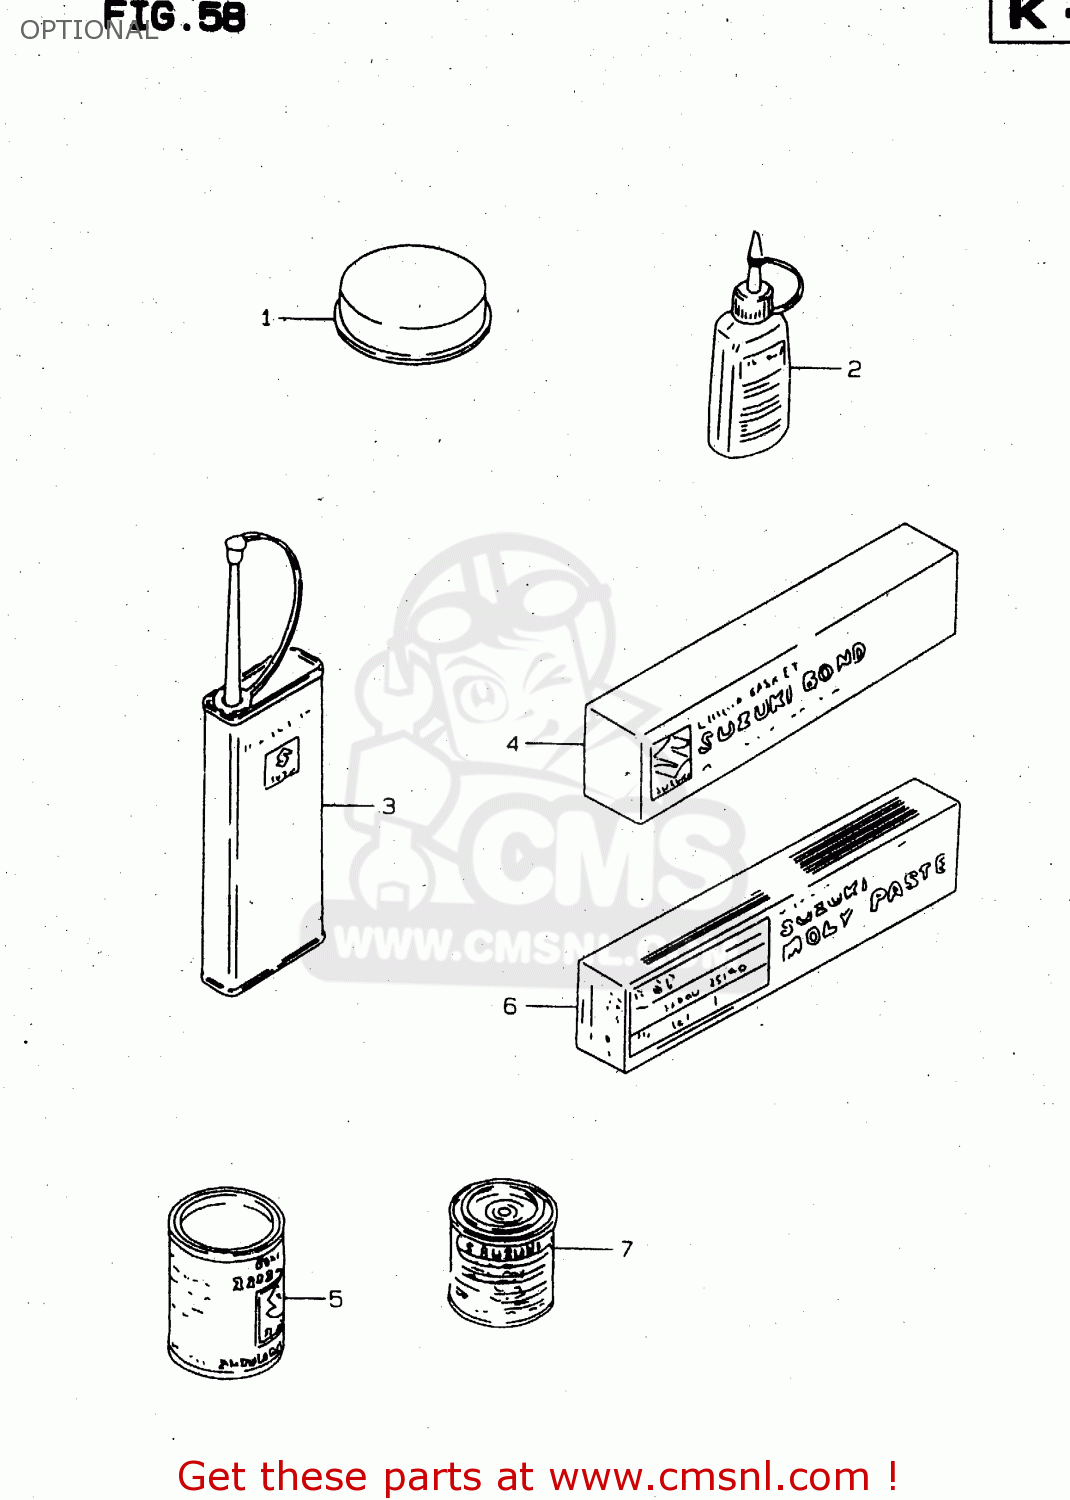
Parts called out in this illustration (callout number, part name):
1	GREASE,PBC FOR BRK PAD 20G
2	THREAD LOCK NO.1342
3	THREAD LOCK NO.1401 CLEAR 200G
4	LIQUID GSKT NO.1215 250G
5	GREASE(C)EP2 LITHIUM 150G
6	SUZUKI MOLY PASTE
7	PAINT(PEARL NOVELTY BLACK)
